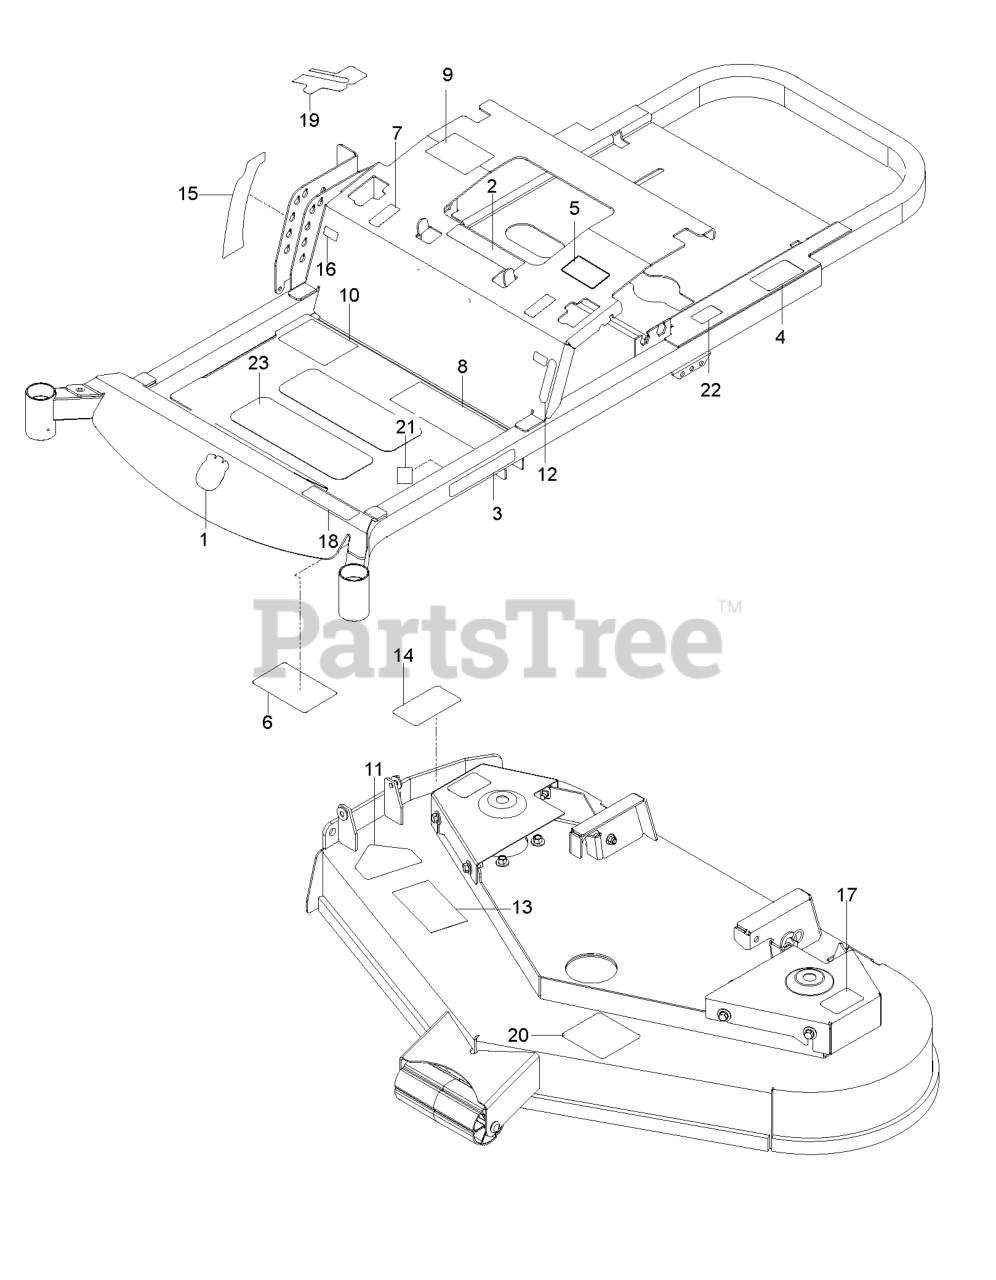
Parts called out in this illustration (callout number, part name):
1	DECAL.AUGER.HUSQ.CROWN.SNOW
2	EURO DECAL-BATTERY WARNIN6
3	RP.DECAL.BADGE.170MM.TEXTLOGO
4	DECAL, DO NOT TOW
5	DECAL, EXITING MOWER
6	DECAL, SERVICE
7	DECAL, MOTION CONTROL
8	DECAL, SAFETY WARNING
9	DECAL, CUSTOMER RESPNSIBILITY
10	DECAL ZTR STARTING
11	DECAL, CPSC
12	DECAL, PARK BRAKE
13	DECAL, EURO SEVERING
14	DECAL.DECK.6MIL./DEF.SHLD.WARN
15	DECAL, DECK HEIGHT, HUSQ
16	DECAL, F.S.T.
17	DECAL.DECK.6MIL.EURO.NOSTEP
18	DECAL.ZTR.RZ4222TF.HUSQVARNA
19	DECAL.CNTRLPANEL.C/START.RZ
20	DECAL, BELT ROUTING
21	DECAL.80.DBA.AUSTRALIA
22	DECAL, ECM, AUSTRALIA
23	ANTI-SKID PAD
